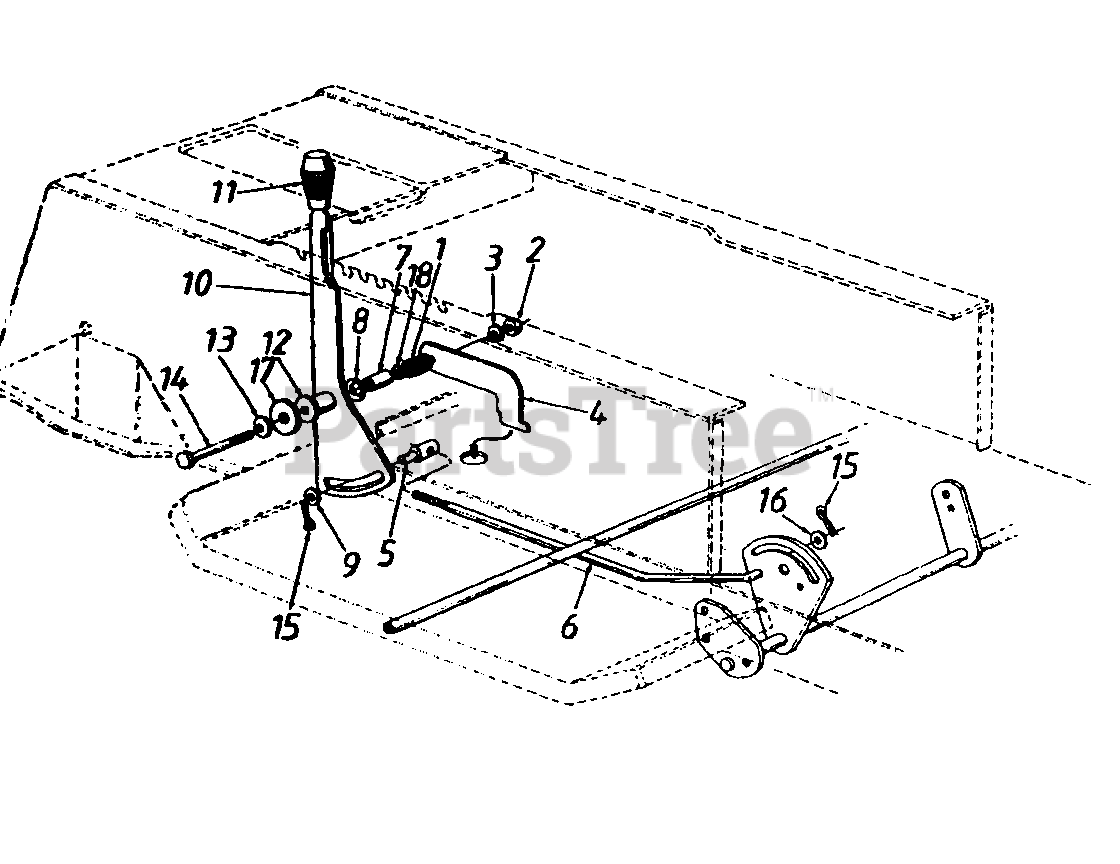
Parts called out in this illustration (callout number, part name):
1	Compression Spring
2	Hex Nut 5/16-18 Thd.
3	L-Wash. 5/16" I.D.
4	Shift Lever Support
5	Ferrule 3/8-24 Thd.
6	Speed Control Rod
7	Spacer 1.56" Lg.
8	Bell-Wash. .505" I.D. x 1"
9	Fl-Wash. .385" I.D. x .87"
10	Speed Selector Lever
11	Shift Knob
12	Spacer 1.46" Lg.
13	Fl-Wash. .345" I.D. x .88"
14	Hex Bolt 5/16-18 x 3.25" Lg.
15	Cotter Pin 3/32" Dia. x 1"
16	Fl-Wash. .469" I.D. x .88"
17	Fl-Wash. .34" I.D. x 2.25"
18	Speed Nut 5/16-18 Thd.
